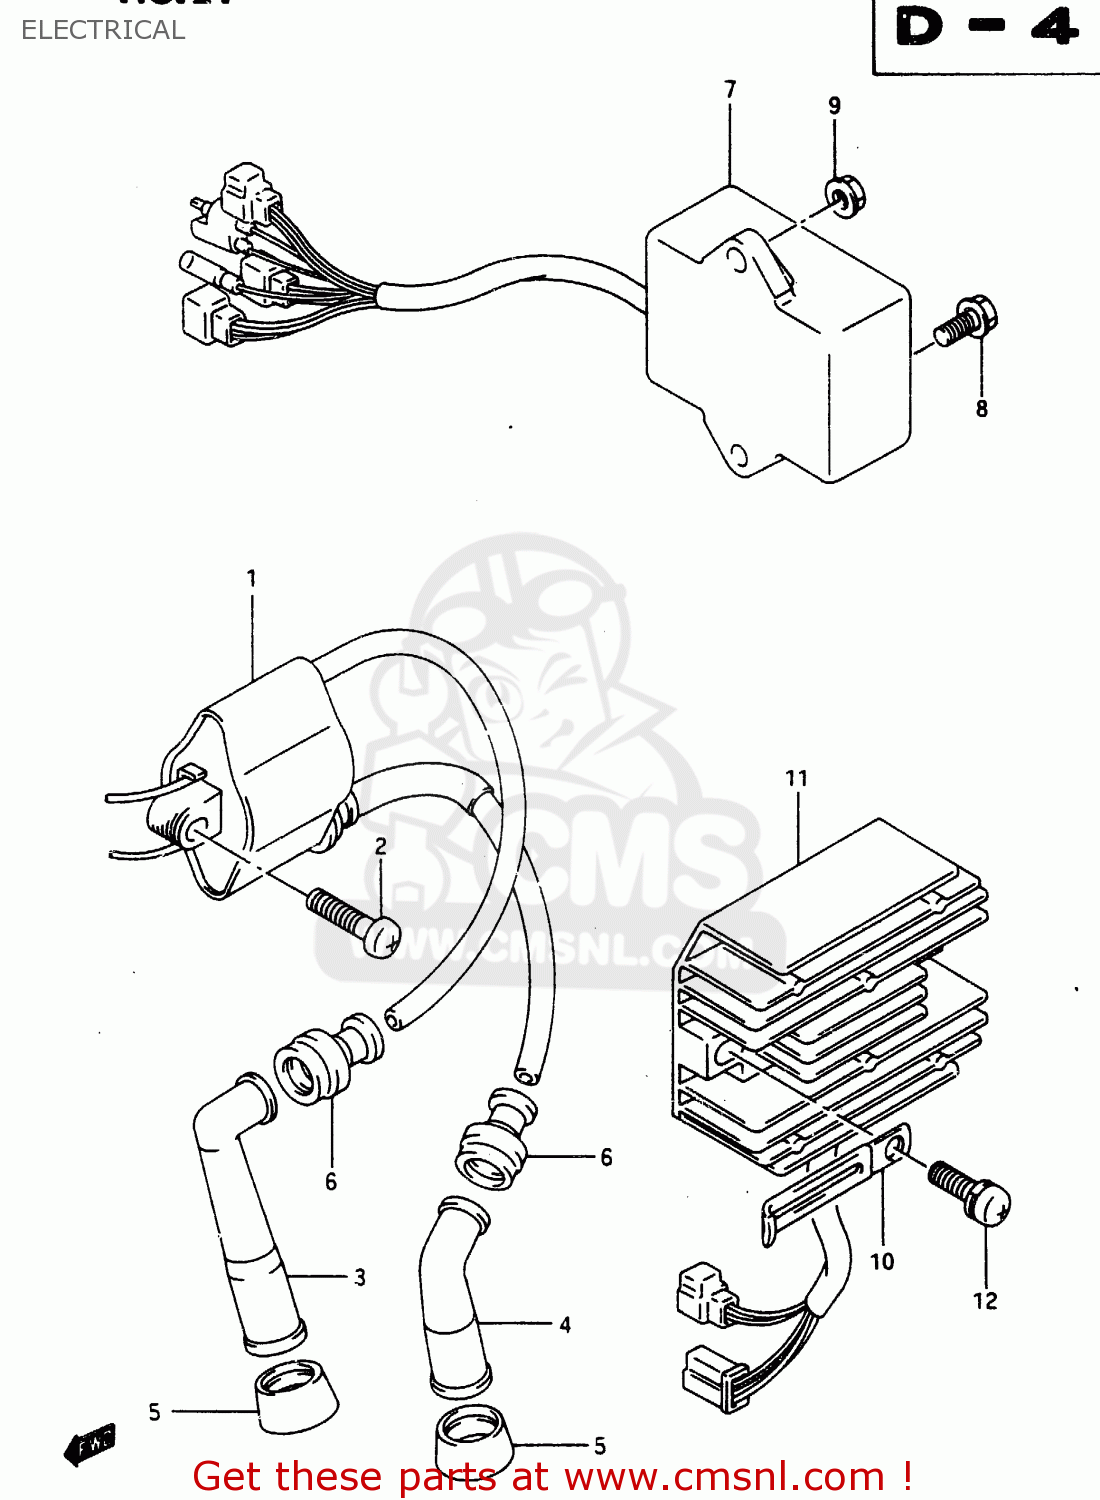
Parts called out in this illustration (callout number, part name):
1	COIL ASSY,IGNITION
2	SCREW
3	CAP ASSY,SPARK PLUG
4	CAP,SPARK PLUG
5	SEAL,SPARK PLUG CAP
6	SEAL,HIGH TENSION CORD
7	CDI UNIT
8	SCREW (6X16) WITH WASHER
9	NUT
10	CLAMP
11	RECTIFIER ASSY
12	SCREW
